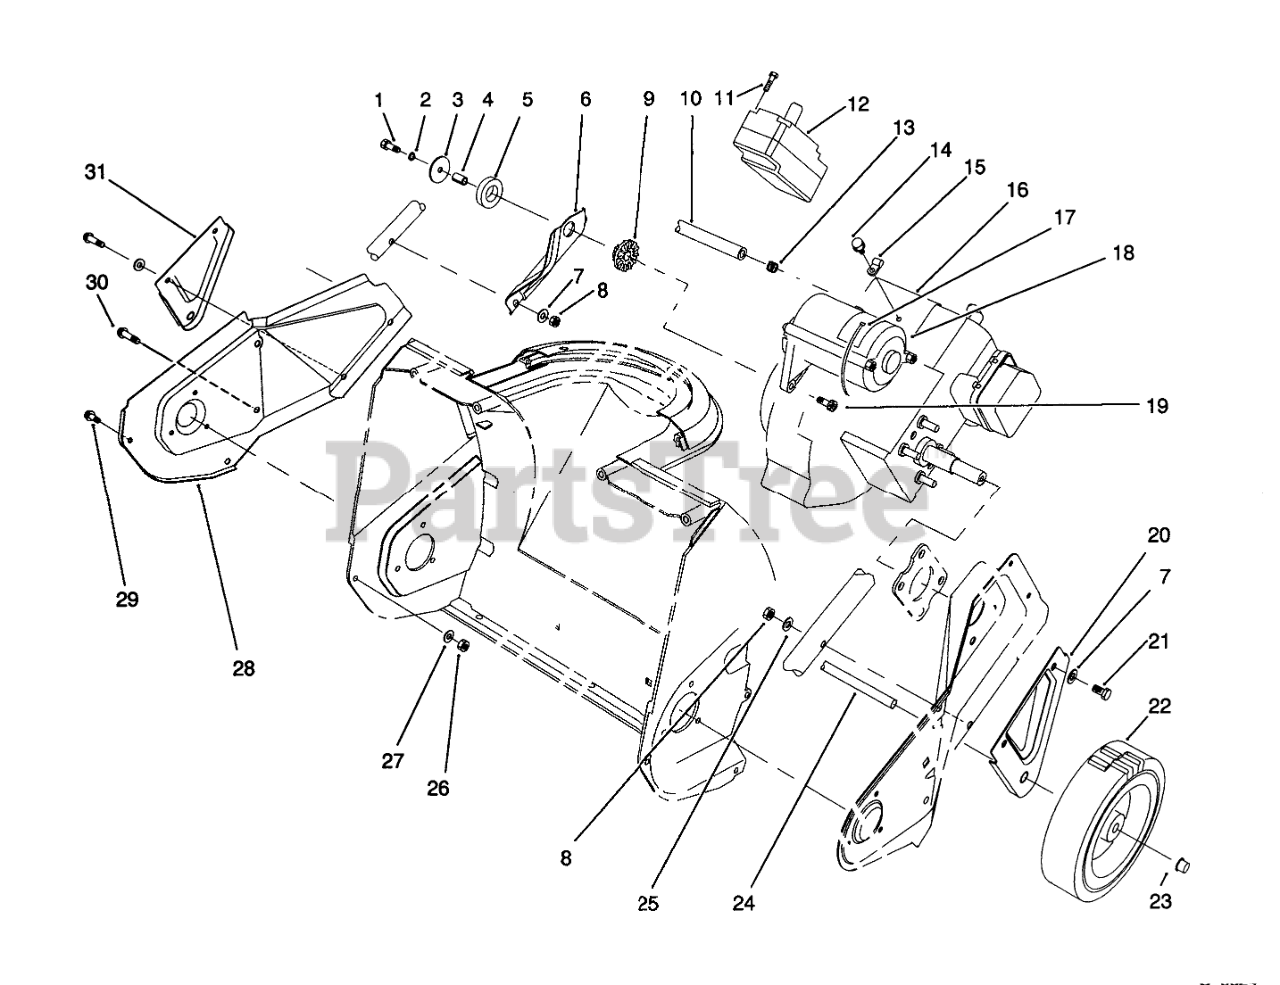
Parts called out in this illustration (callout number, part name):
1	SCREW-HH
2	WASHER-LOCK
3	WASHER-FLAT
4	SPACER-TUBULAR
5	Ring-Isolator
6	Support-Engine
7	WASHER-FLAT
8	NUT-LOCK, NI
9	BUSHING-ISOLATOR
10	LINE-GAS
11	SCREW-PLASTITE
12	Motor Switch Housing Ass-y (Model No. 38176 Only)
13	Clamp
14	SCREW-HWH
15	CLAMP
17	TIE-CABLE
18	Starter Motor Assembly
19	Screw-Thread Forming
20	Bracket-Wheel
21	SCREW-HH
22	WHEEL
23	RETAINER-PUSH ON
25	WASHER
26	NUT-LOCK, NI
27	WASHER-FLAT
28	Sideplate-RH
30	SCREW-PLASTIC
31	Bracket-Wheel
